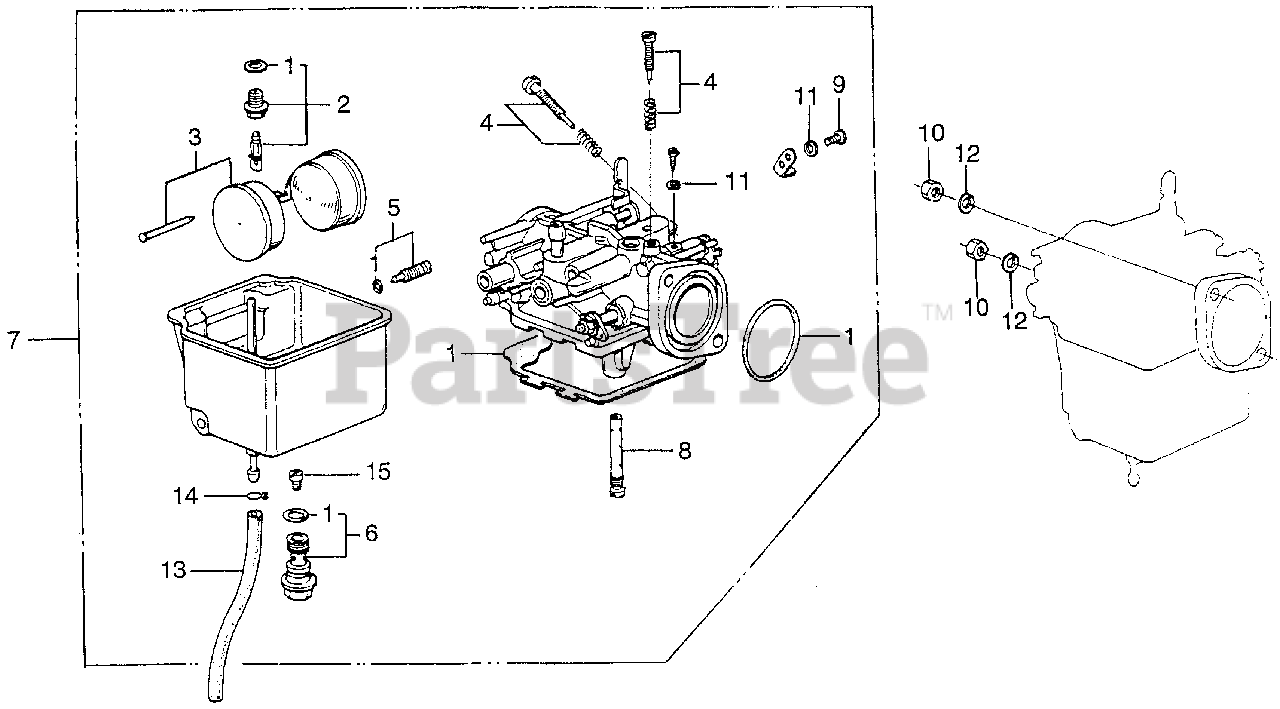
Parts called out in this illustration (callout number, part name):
1	GASKET SET
2	VALVE SET, FLOAT
4	SCREW SET A (NOT AVAILABLE)
5	SCREW SET, DRAIN (NOT AVAILABLE)
6	SCREW SET B (NOT AVAILABLE)
7	CARBURETOR ASSY. (NOT AVAILABLE)
8	NOZZLE, MAIN (NOT AVAILABLE)
9	SCREW, PAN (3X7) (SOURCE: VINTAGE PARTS INC.)
10	NUT, HEX. (6MM)
11	WASHER, SPRING (3MM)
12	WASHER, SPRING (6MM)
13	BULK HOSE, FUEL (3.5X3000) (3.5X150)
14	CLIP, TUBE (B7)
15	JET, MAIN (#92)
